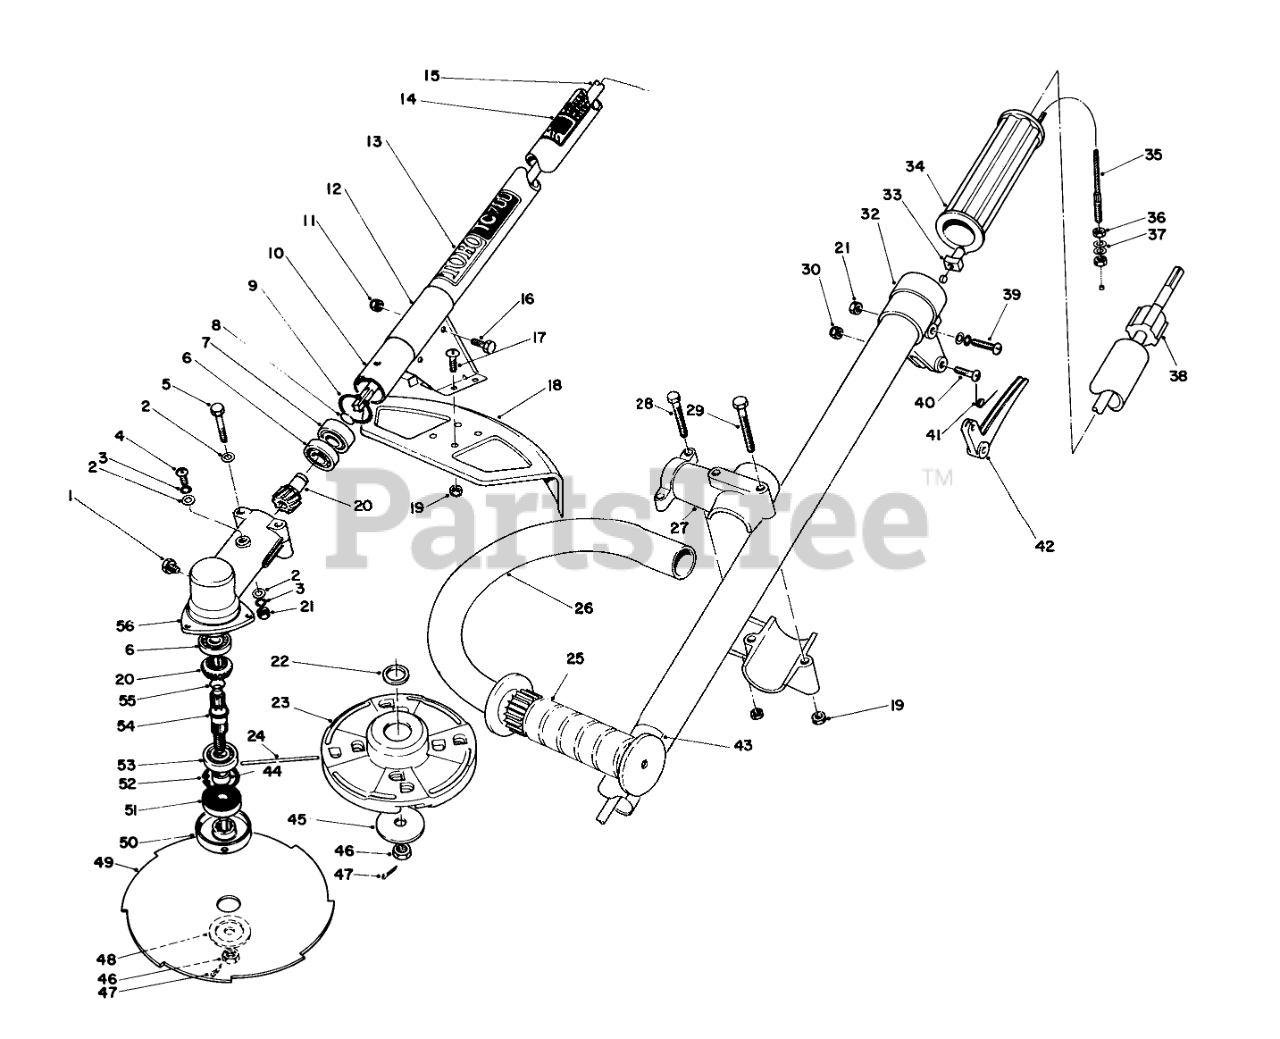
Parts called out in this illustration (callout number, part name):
2	WASHER
3	Washer
4	Screw
6	Ball Bearing
7	Ball Bearing
8	Circlip
9	Circlip
10	Housing Assembly
11	NUT-LOCK, NI
12	Bracket-Shield
13	Decal-TC700
14	Decal
15	Shaft Drive
16	SCREW-HH
17	SCREW-PPH
18	Shield
19	NUT-LOCK, NI
20	Gear Set
21	Nut
22	SPACER
23	Cutter Head (Incl. Ref. #22)
24	LINE PACK (100)
25	LH GRIP
26	Tube-Handle
27	Clamp-"J" Handle
28	10-24X1-1/8 RND HD MS
29	10-24X1-3/4 RND HD MS
32	Bracket, Trigger
33	SPACER
34	GRIP - WILLMAR
35	Throttle Cable
37	Washer
38	Bushing
39	SCREW
40	Screw
41	Spring Return
42	Throttle Trigger
43	Decal Warning
44	Spacer
45	WASHER
47	1/16 X 1 LG COTTER PIN
48	Blade Adapter Kit (Incl. Ref. #46 & 47)
49	8" Blade (8T)
50	Plate-Blade Fixing
51	Oil Seal
52	Circlip
53	Ball Bearing
54	Shaft P.T.O.
55	Circlip
56	Gear Housing
